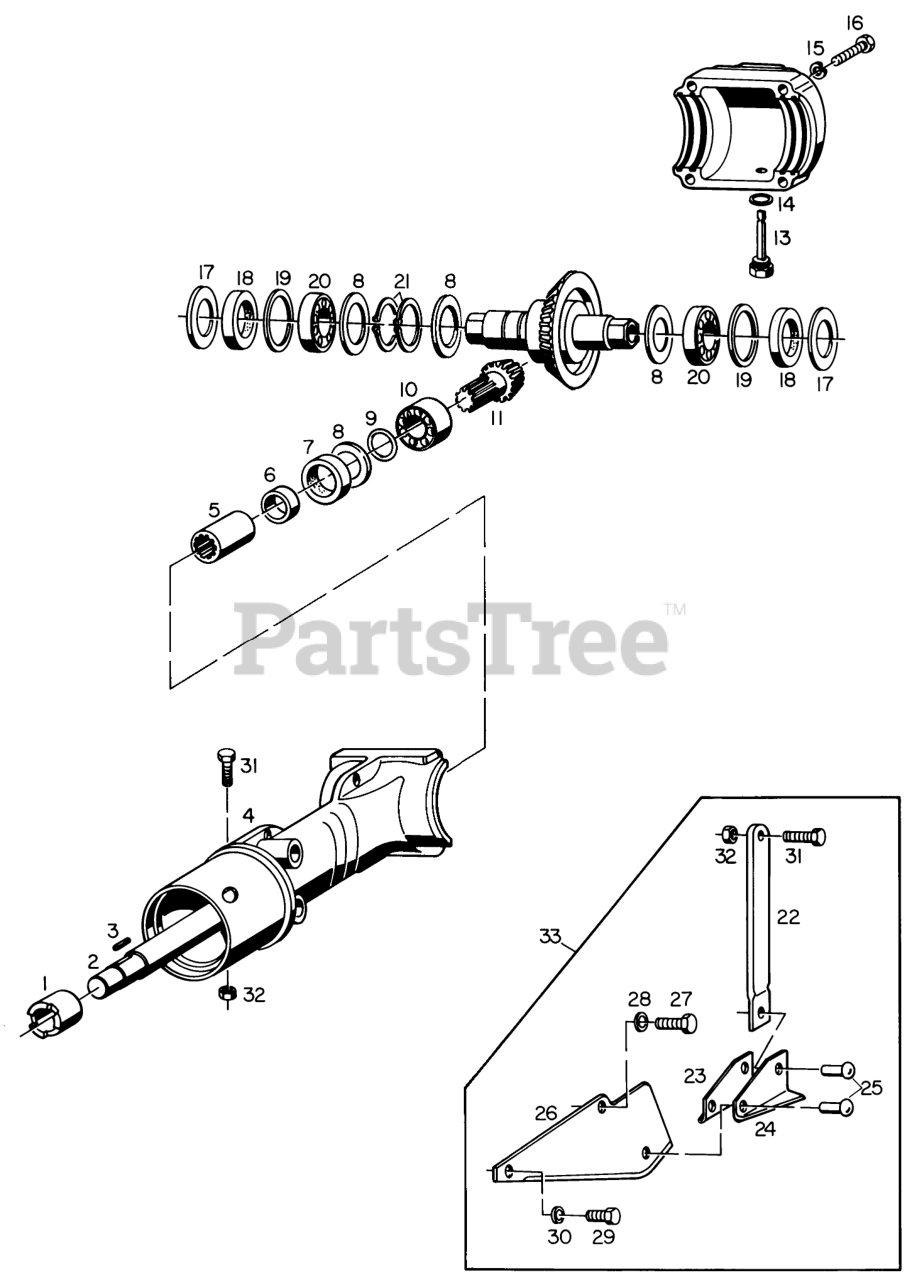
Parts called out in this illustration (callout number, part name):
1	Drive Ratchet
2	Drive Shaft
4	Housing Assy. (Includes 15 & 16)
5	Sleeve
6	Spacer
10	Bearing
11	Matched Pinion & Ring Gear Assembly
13	Oil Level Dipstick
14	Gasket
15	Washer
17	Washer
19	Washer
20	Bearing
21	Retaining Ring
22	Mounting Arm
23	Depth Control-Right
24	Depth Control-Left
25	Rivet
26	Hoe Positioner
28	Lockwasher
30	Lockwasher
33	Hoe Positioning Assembly
